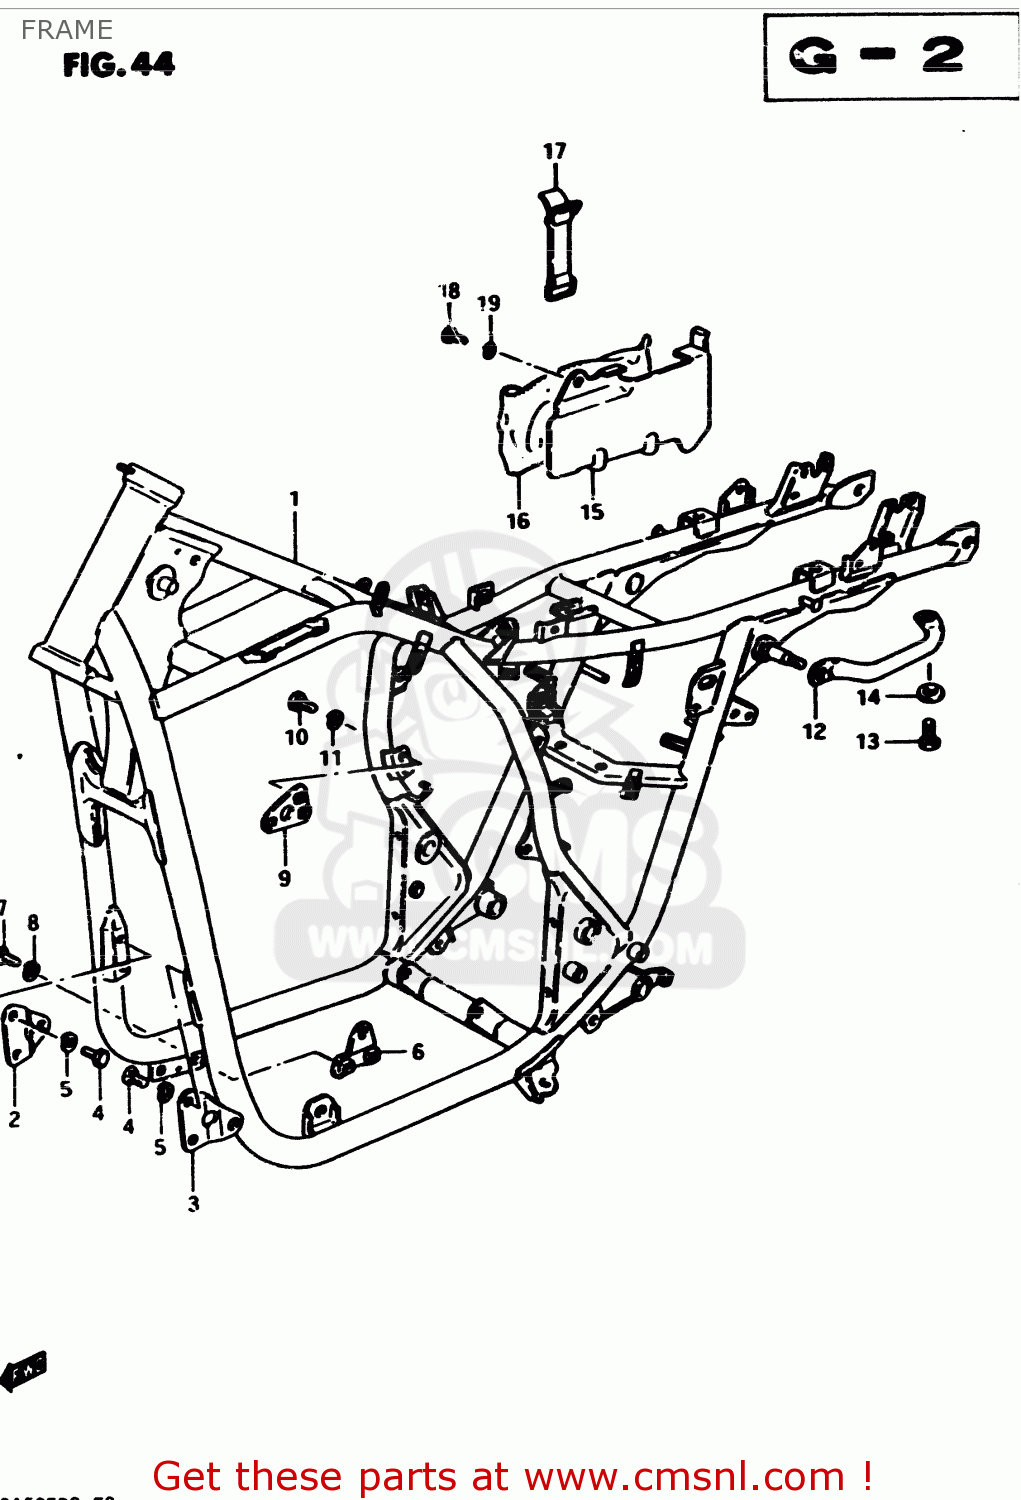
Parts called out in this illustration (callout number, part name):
1	FRAME (BLACK)
2	PLATE,ENG MTG NO.1,R
3	PLATE,ENGINE MOUNTING,LEFT
4	BOLT
5	LOCK WASHER
6	PLATE,MOUNTING NO.2,LEFT
7	BOLT
8	LOCK WASHER
9	PLATE,MOUNTING NO.4,LEFT
10	BOLT
11	LOCK WASHER
12	GRIP,FRAME HANDLE
13	BOLT
14	WASHER
15	HOLDER,TOOL
16	TOOL SET
17	BAND
18	BOLT
19	LOCK WASHER
